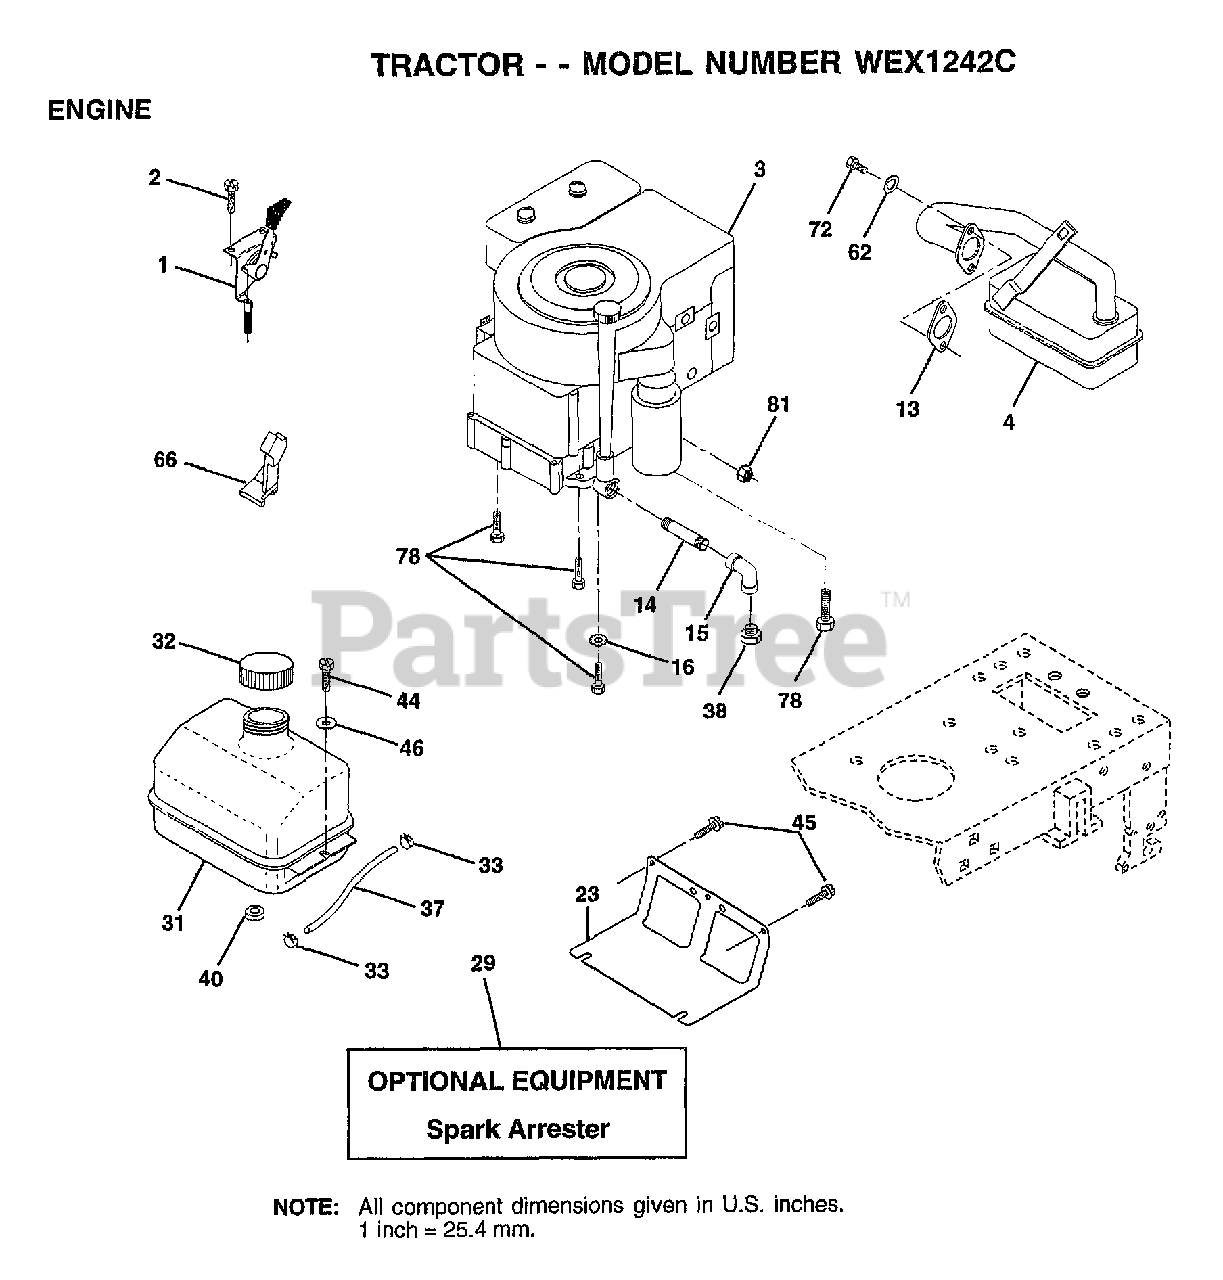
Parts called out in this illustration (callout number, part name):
1	CONTROL.THTL.23.5
2	SCREW LT
4	MUFFLER
14	PIPE NIPPLE
15	ELBOW
16	LOCKWASHER
23	SHIELD BROWNING
31	TANK.FUEL.LT.
32	CAP ASM FUEL
33	HOSE CLAMP
37	LINE FUEL
44	SCREW
45	SCREW
46	WASHER
62	LOCKWASHER
66	"STOP,DASH THROTT"
72	SCREW
78	SCREW
81	NUT
